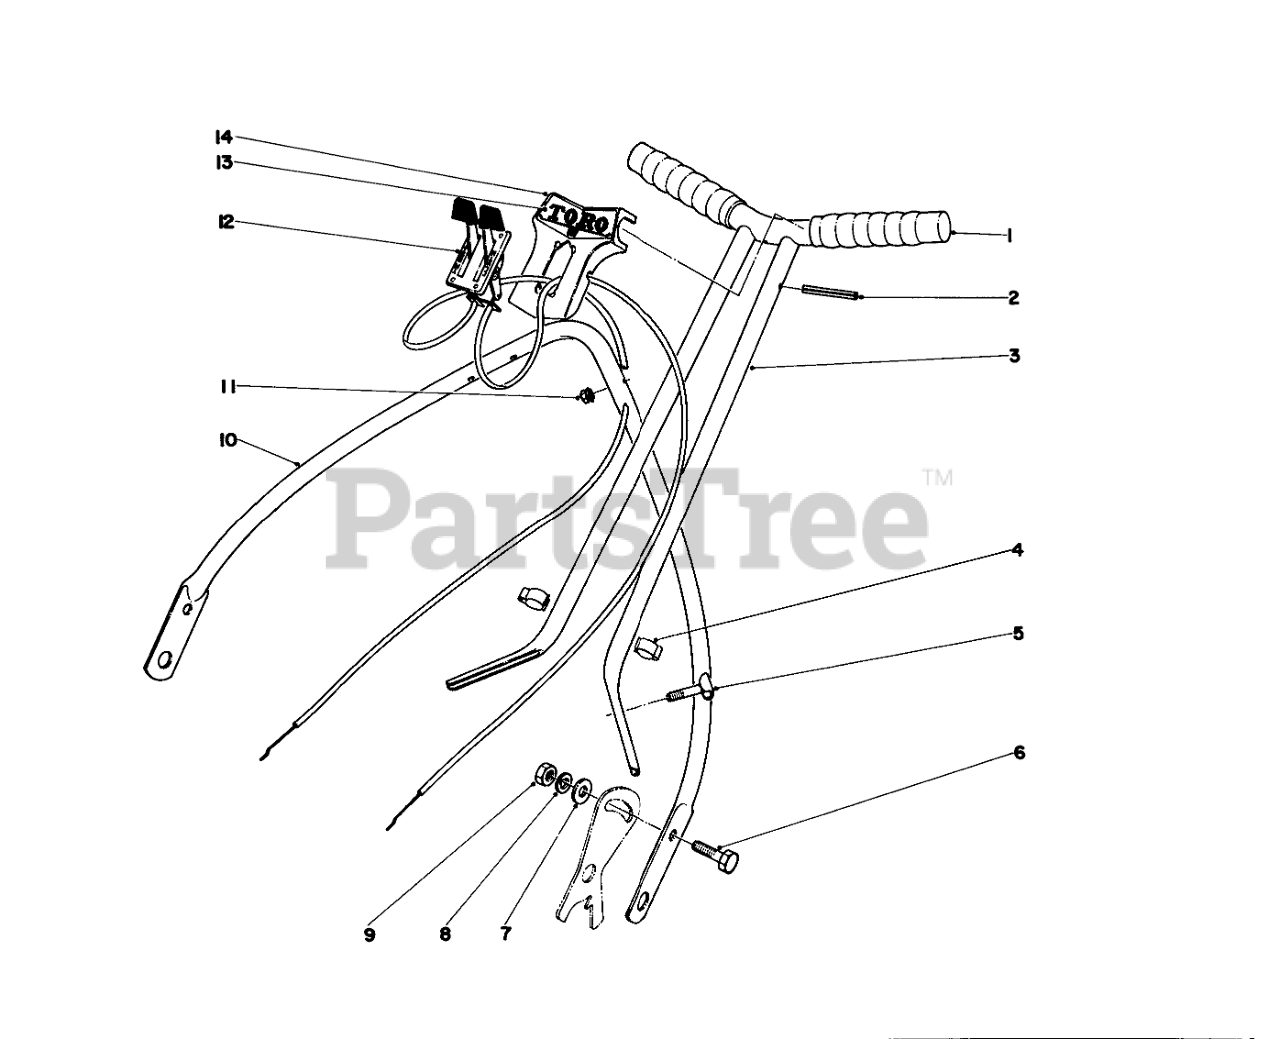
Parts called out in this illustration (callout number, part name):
1	Handle Clip
2	PIN-ROLL
3	Upper Handle
4	CONTROL WIRE CLIP
6	SCREW-HH
7	WASHER-PLAIN
8	WASHER-LOCK
9	NUT-HEX
10	Lower Handle
11	NUT-KEPS
12	Control Assembly
13	Decal
14	Cover Plate
